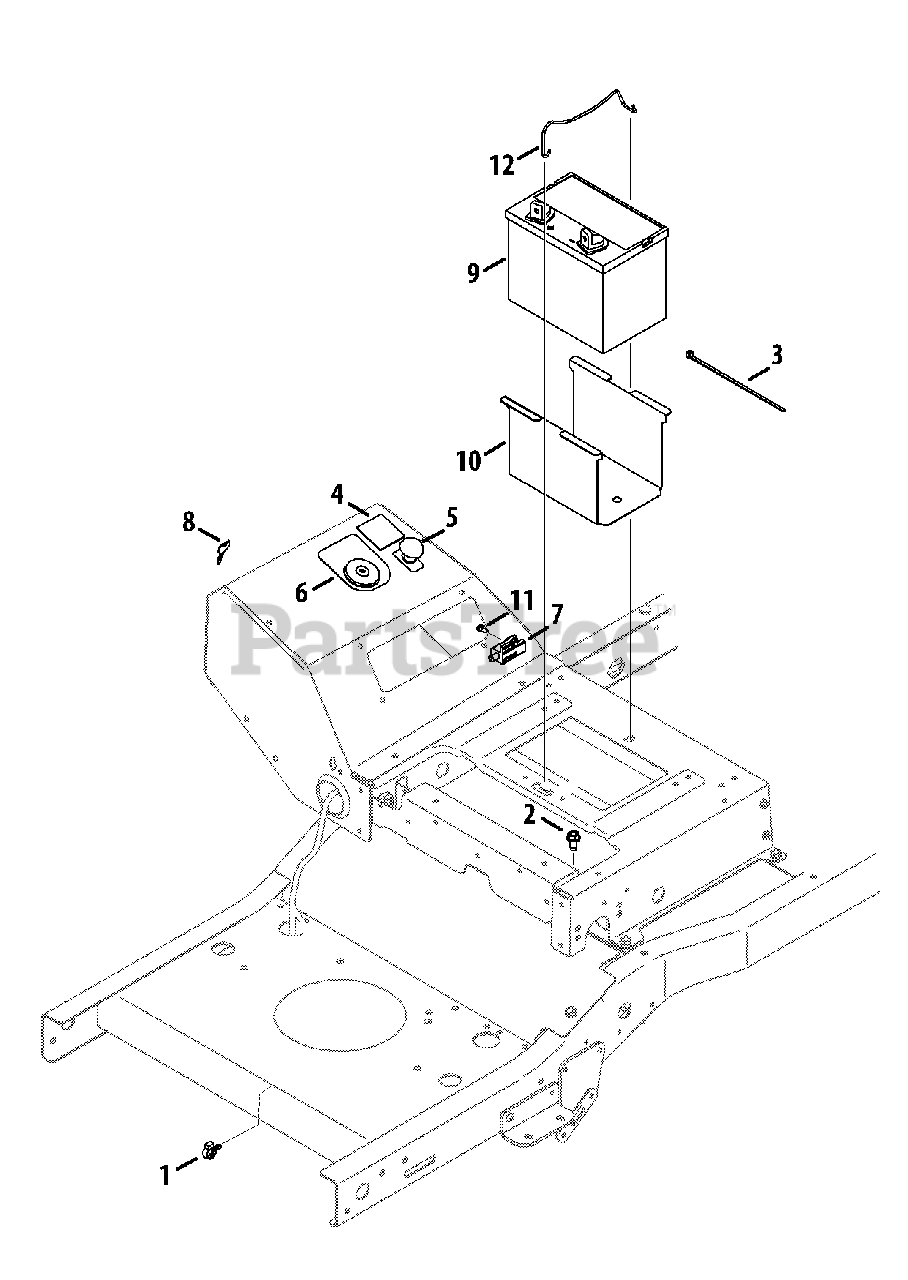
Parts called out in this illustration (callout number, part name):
1	Electrical Conduit Clip, 1/2
2	Screw, 3/8-16 x .75
3	Cable Tie, 3/16 x .05 x 7.4
4	Hour Meter/Service Minder
5	Electric PTO Switch
6	Key Switch
7	Interlock Switch
8	Key, Assembly
11	Shoulder Screw, #10-32 x .500
12	Battery Rod
